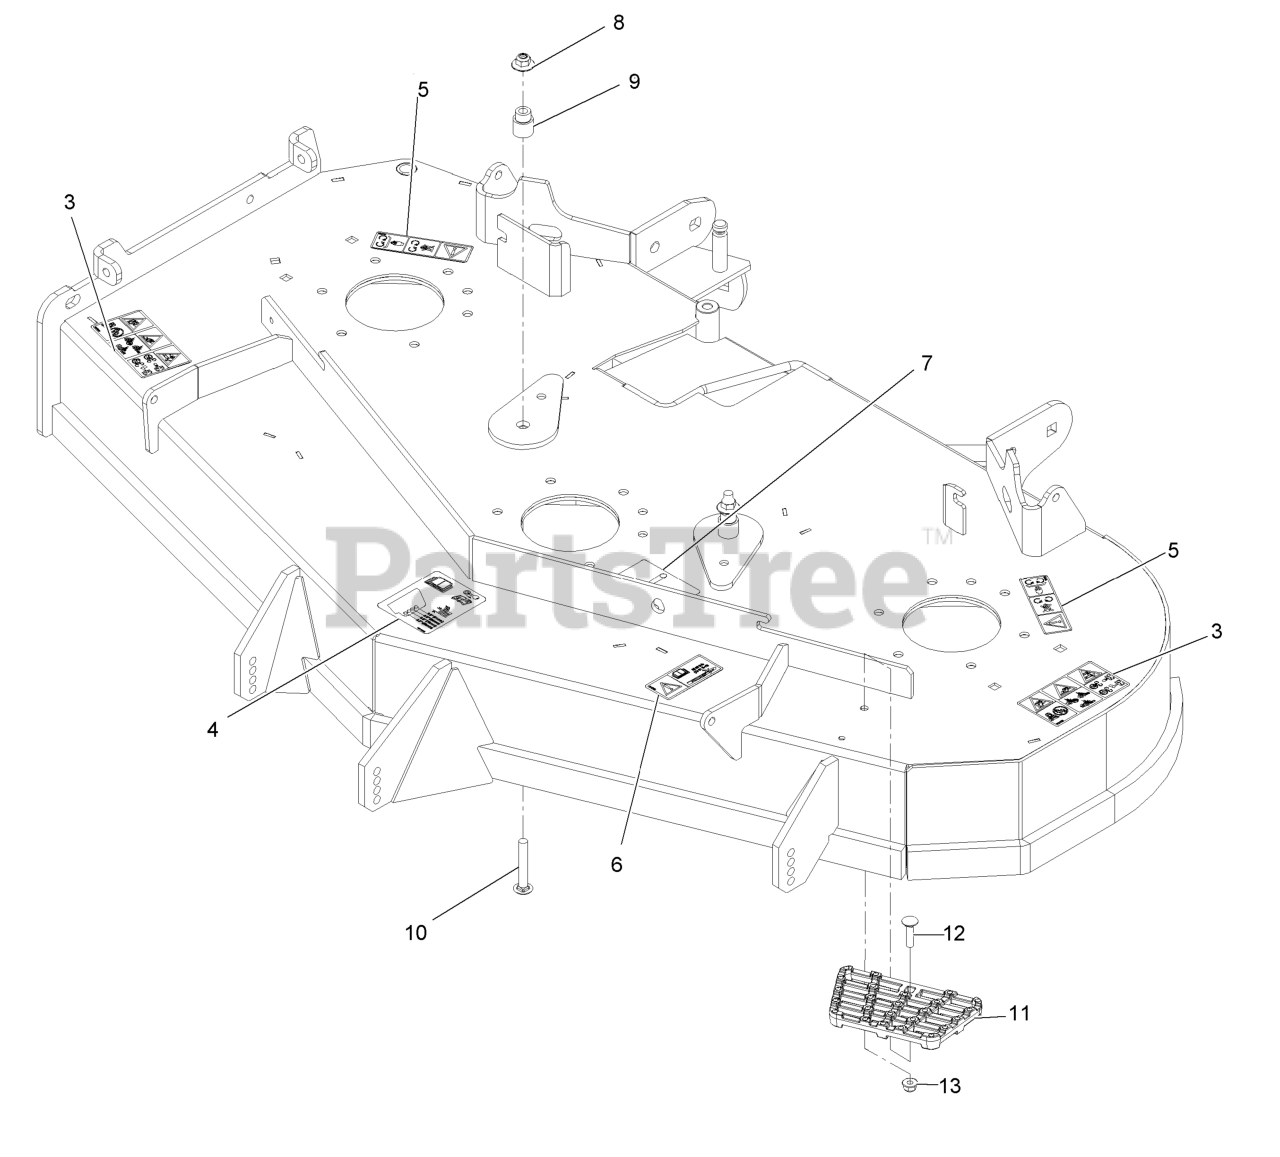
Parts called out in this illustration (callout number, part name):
3	Decal-Danger Thrown Objects
4	Decal-Roller, Anti-Scalp
5	Decal-Cover, Missing
6	Decal-Bolt Torque
7	Decal-Belt Routing
8	Nut-Nyloc 3/8-16 Flg
9	Bushing, Idler
10	Bolt-Carriage 3/8-16 X 2 1/2
11	Step-Deck
12	Bolt-Carriage 5/16-18 X 1 1/4
13	Nut-Nyloc 5/16-18 Flg
